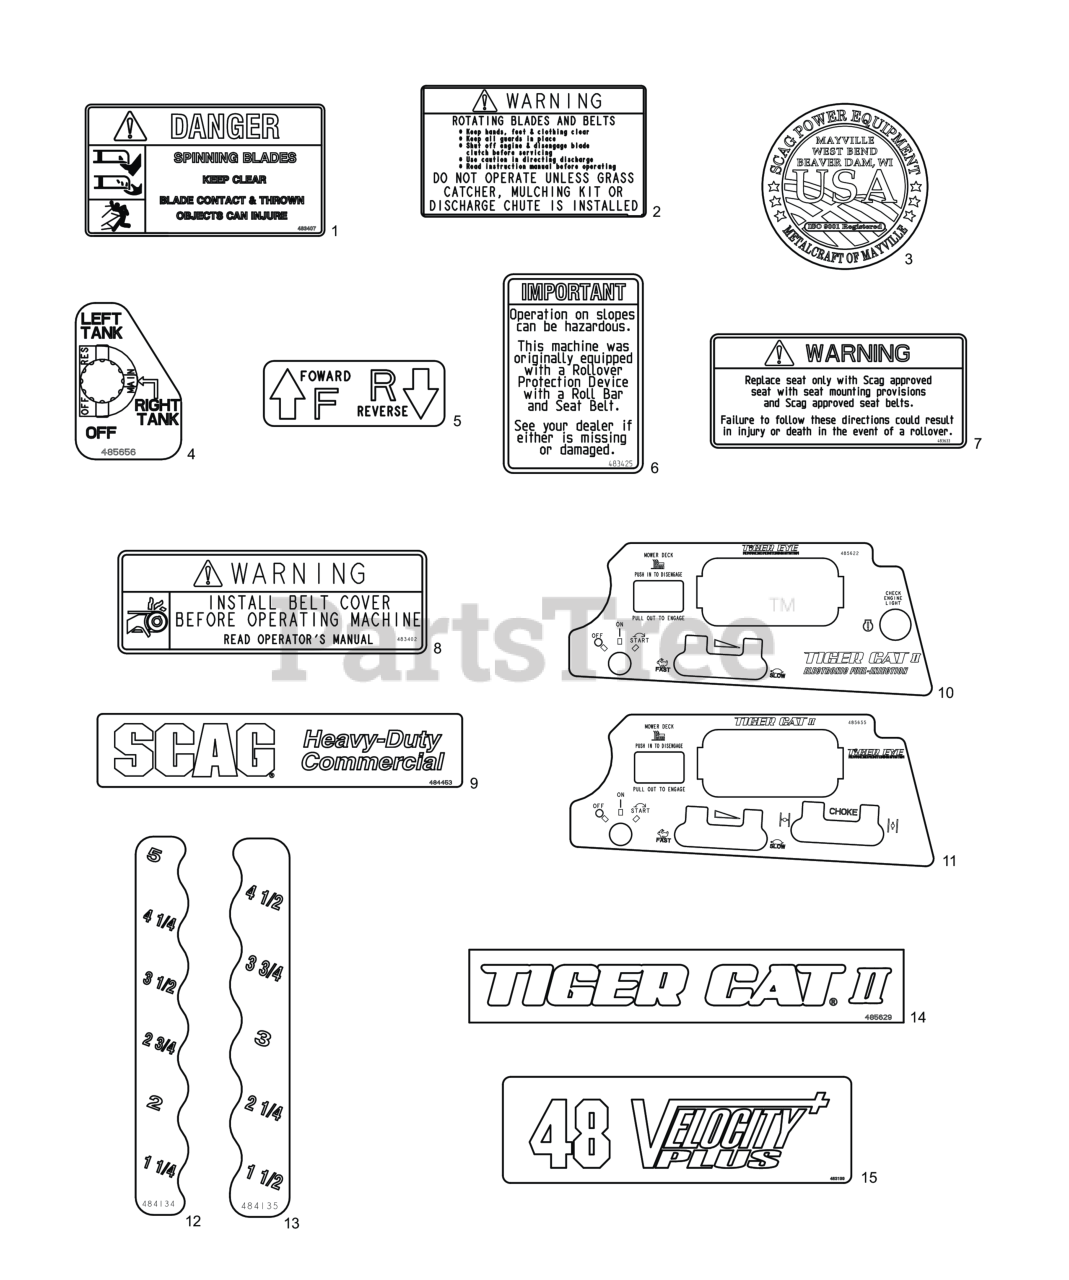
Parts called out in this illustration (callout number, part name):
1	Decal, Danger-Spinning Blades
2	Decal, Warning - Rotating Blades
3	Decal, Metalcraft - USA
4	Decal, Fuel Valve Position
5	Decal, Traction Control
6	Decal, ROPS
7	Decal, Seat Replacement
8	Decal, Warning - Belt Cover
9	Decal, Scag Heavy Duty Commercial
10	Decal, Instrument Panel - EFI
11	Decal, Instrument Panel
12	Decal, Deck Height - LH
13	Decal, Deck Height - RH
14	Decal, Tiger CatII
15	DECAL, VELOCITY PLUS - 48
